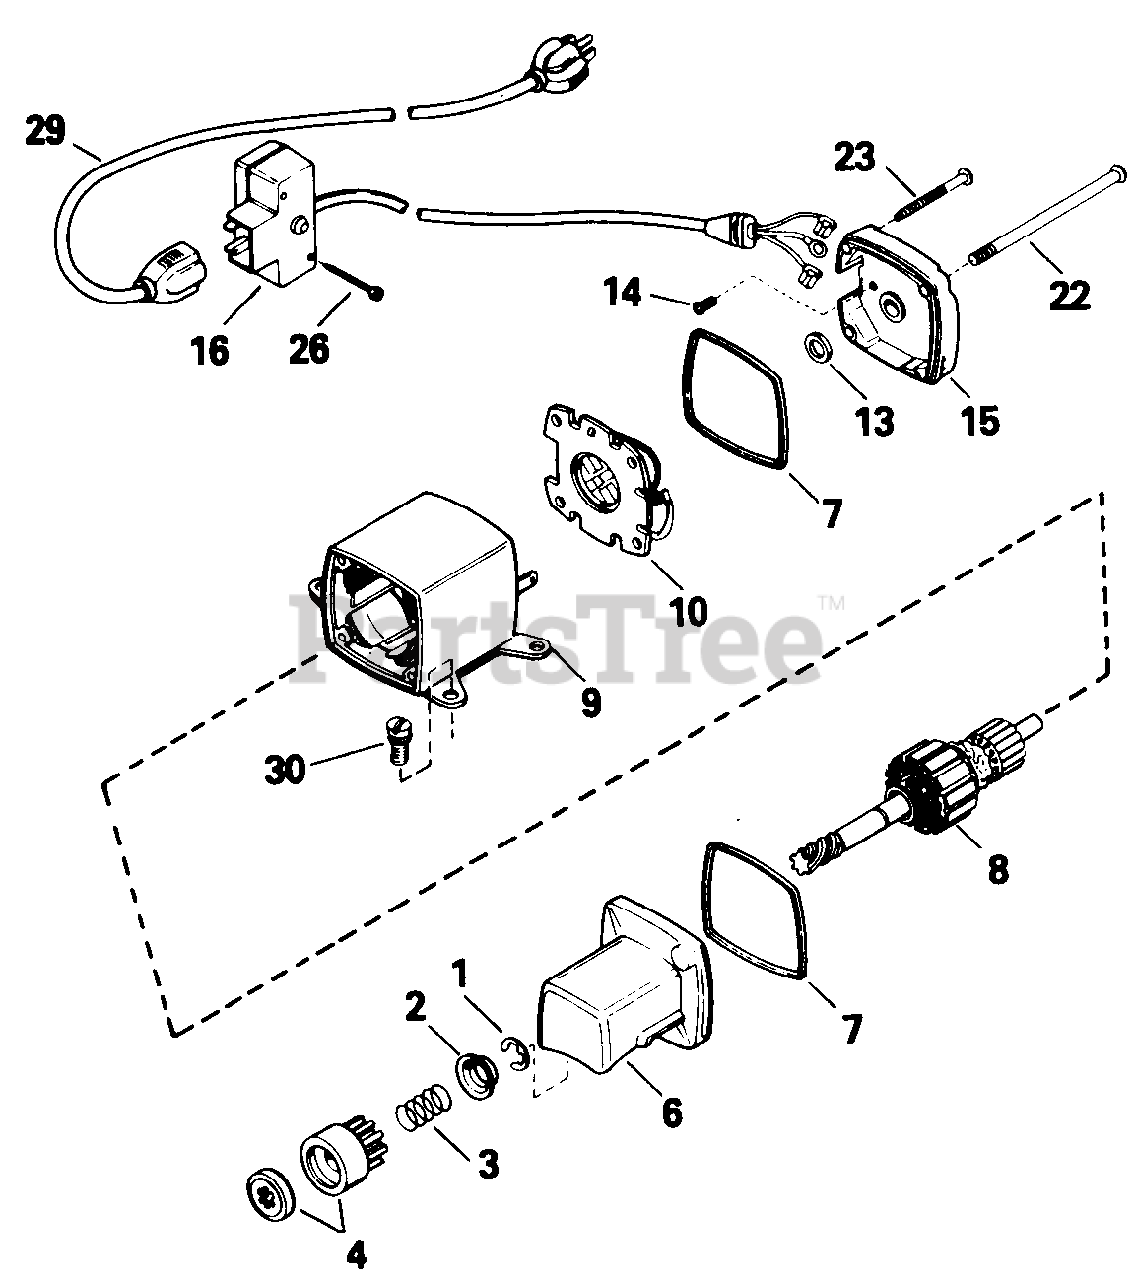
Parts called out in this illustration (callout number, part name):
1	Ring, Retainer
2	Retainer, Spring
3	Spring, Anti-Drift
4	Nut & Gear
6	Cap Ass'y., Drive End
8	Armature
9	Housing Ass'y.
10	Card Ass'y. Brush
13	Washer, Thrust
14	Screw, Ground
15	Cap Ass'y., Commutator End
16	Box Ass'y., Switch
22	Bolt, Case
23	Screw, Grounding
26	Screw, Hex Hd. Self-Tap, 6-32 x 21/2
29	Cord, Extension
30	Screw, Hex Hd. Self-Tap, 1/4-20 x 11/16
